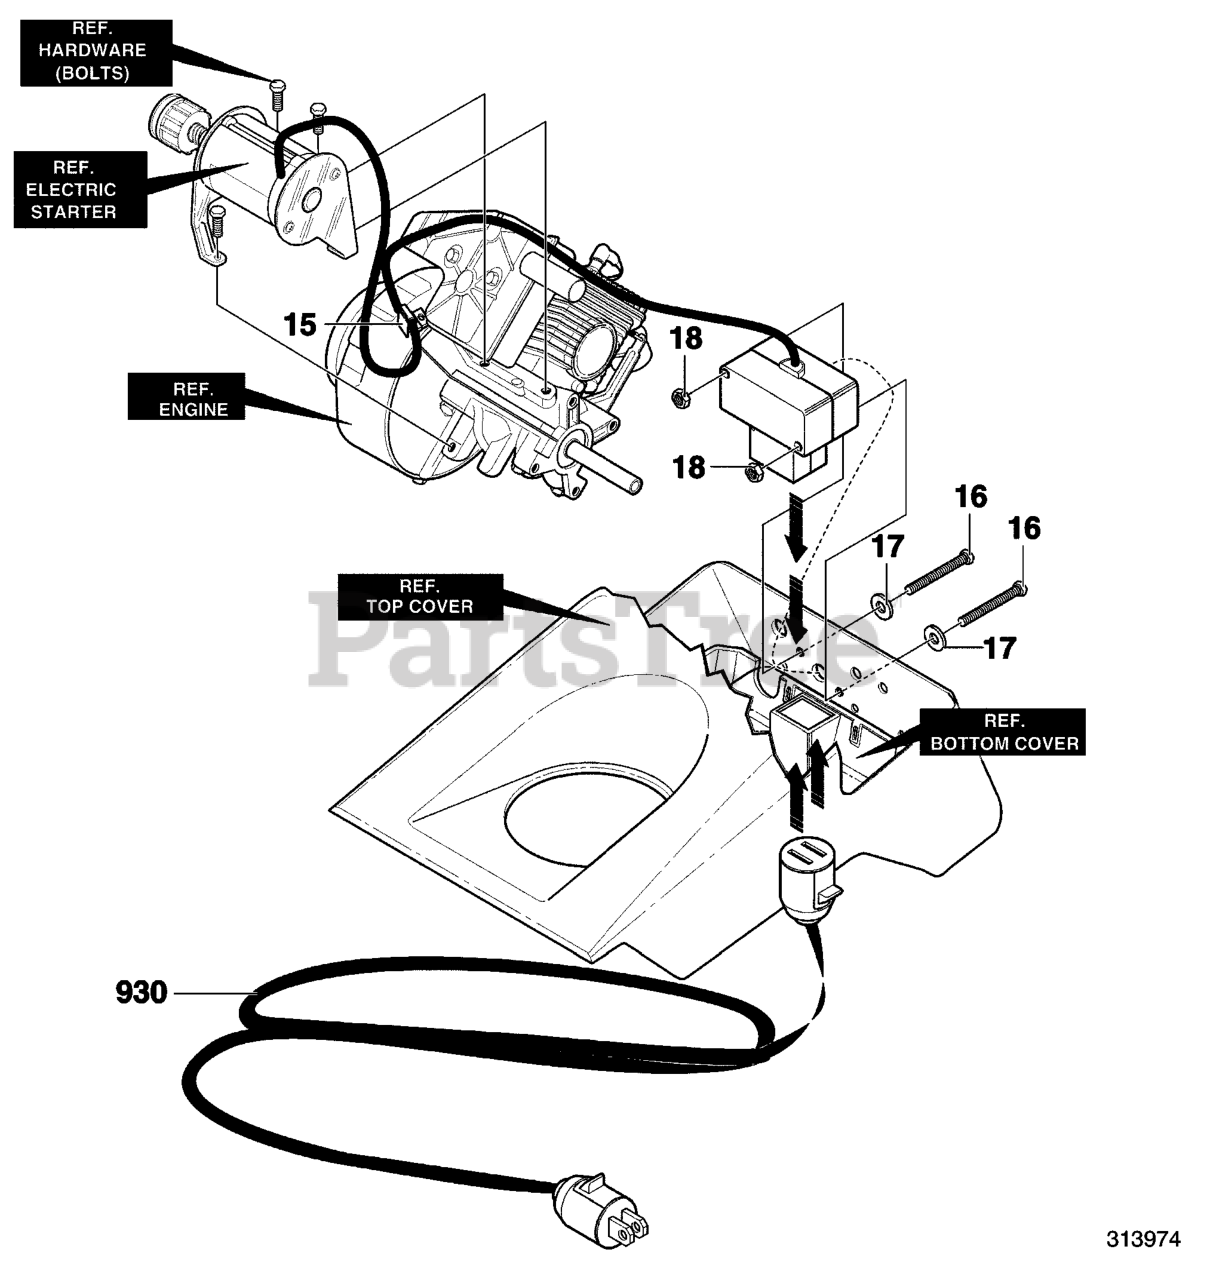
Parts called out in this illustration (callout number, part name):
15	RETAINER
16	SCREW #8-32X3.00
17	WASHER, FLAT .188X.38X.040
18	NUT, #8-32X3.00
930	CORD EXTENSION
